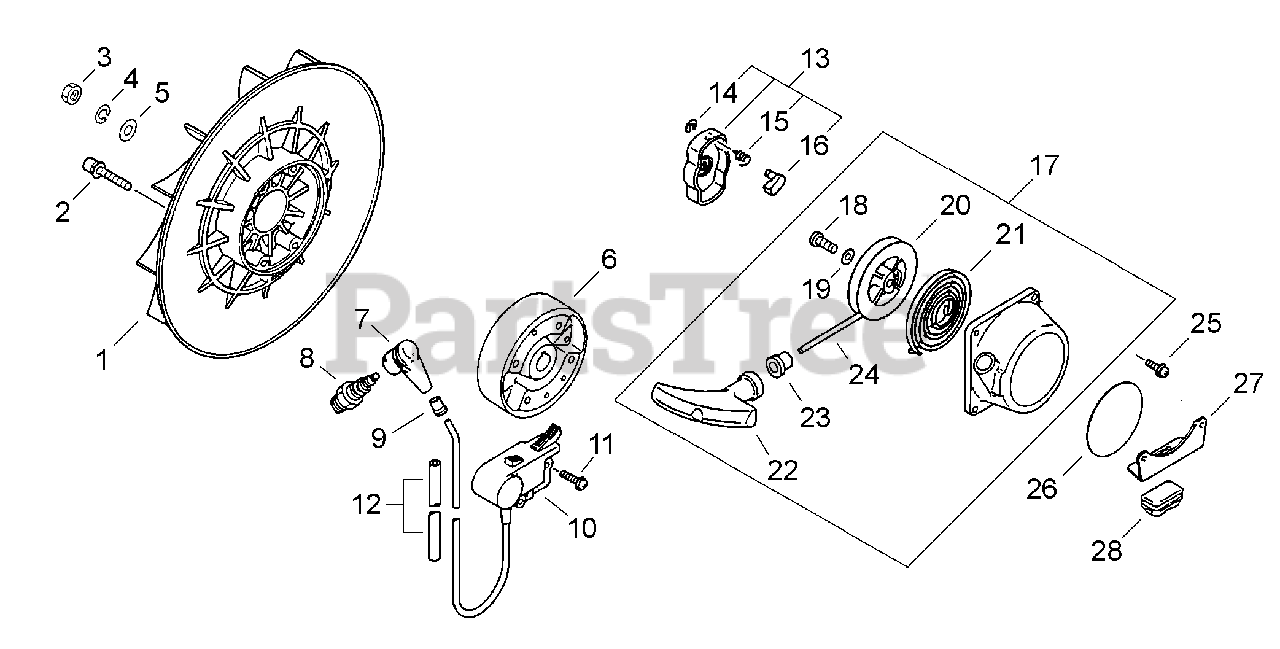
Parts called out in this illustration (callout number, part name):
2	BOLT 5×35
4	WASHER, SPRING 10
5	WASHER, SPRING 10
6	FLYWHEEL
7	CAP, SPARK PLUG
8	SPARK PLUG - BPMR7A
9	ADAPTOR, SPARK PLUG - CAP
10	COIL, IGNITION
11	SCREW 5×18
12	TUBE, IGNITION COIL 6×8×340
13	PAWL ASSY, STARTER
14	E-RING 4
15	SPRING, RETURN
16	PAWL, STARTER
17	STARTER ASSY, RECOIL
19	WASHER
20	REEL, ROPE
21	SPRING, RECOIL
22	GRIP, STARTER
23	GUIDE, ROPE
24	ROPE, STARTER 3.8×1400
25	SCREW 4×18
26	LABEL, ECHO
27	PLATE, ANGLE
